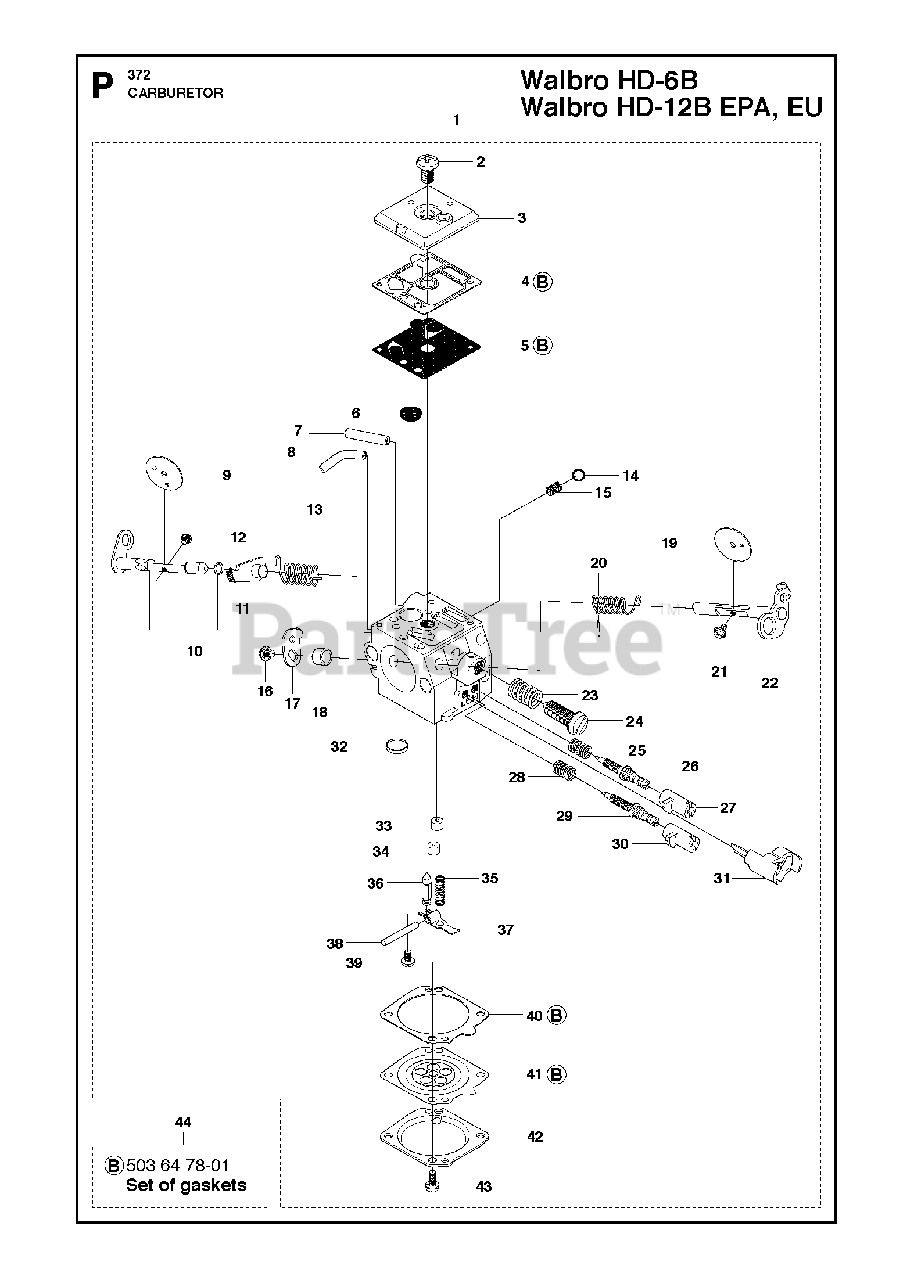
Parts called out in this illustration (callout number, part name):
1	CARBURETOR WALBRO HD-6B
1	CARBURETOR HD-12B EPA WALBRO
4	GASKET, PUMP SIDE
5	PUMP DIAPHRAGM
6	FUEL INLET SCREEN
9	CHOKE FLAP
10	CHOKE SHAFT
11	LEVER
19	THROTTLE FLAP
21	SCREW SHUTTERS
23	SPRING
26	SCREW
26	IDLE SCREW
27	LIMITER CAP
29	IDLING SCREW
29	ADJUSTING SCREW
30	LIMITER CAP
31	CAP
32	WELCH PLUG
33	JET
34	JET
35	SPRING
36	INLET NEEDLE
38	FULCRUM PIN
40	GASKET
41	GASKET
42	IMPULSE COVER
43	RP SCREW W/ WASHER
44	GASKET SET
